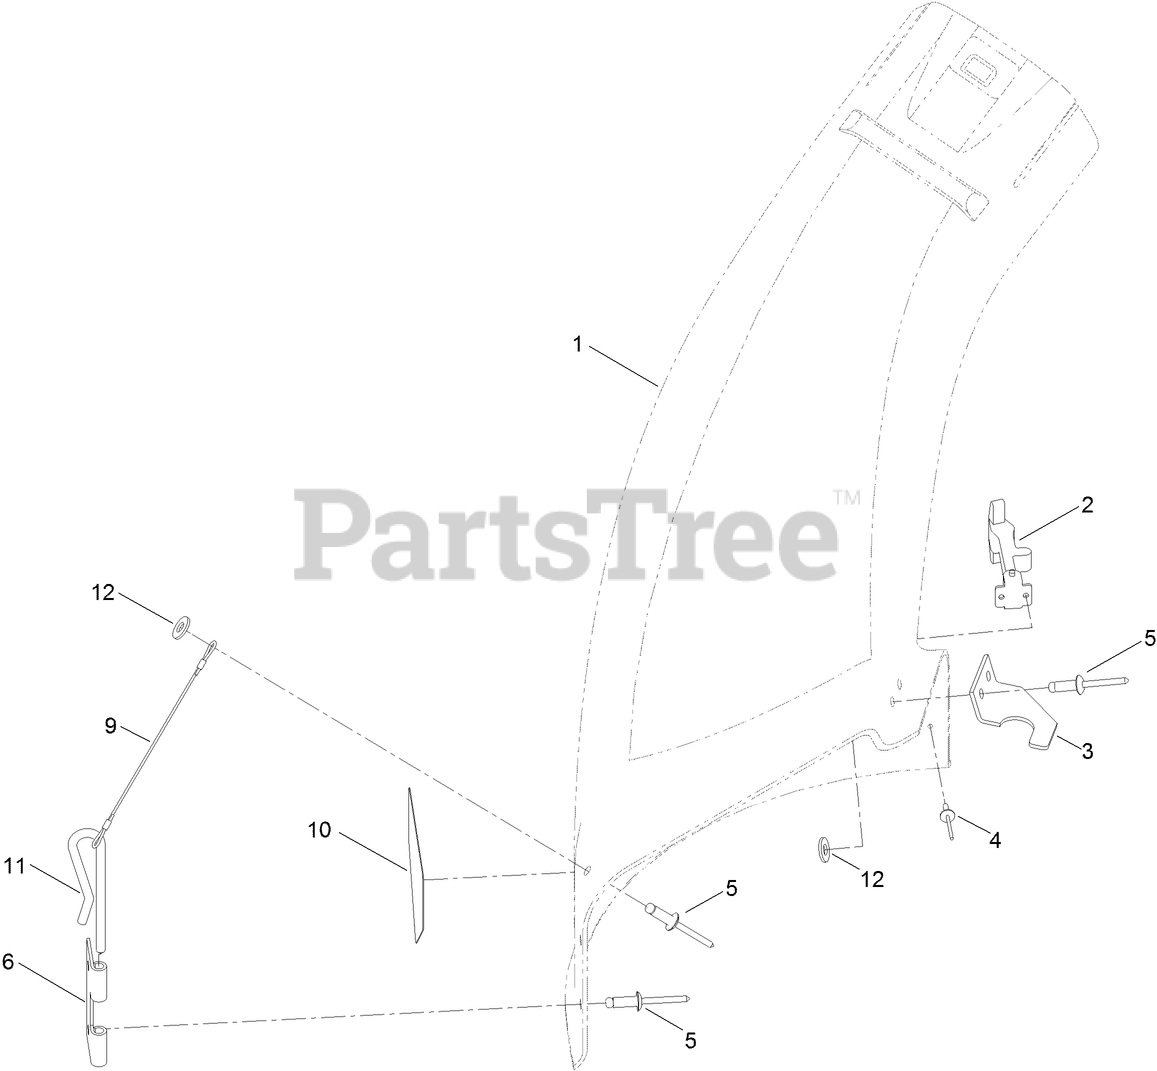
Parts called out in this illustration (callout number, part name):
1	ELBOW-BAGGER, 38 INCH
2	HANDLE ASM
3	LATCH-ELBOW, BAGGER
4	RIVET-POP
5	RIVET-BLIND
6	BRACKET-MOUNTING, CHUTE
9	LANYARD
10	DECAL-DANGER, CE
11	PIN-LOCKING, CHUTE
12	WASHER-FLAT
